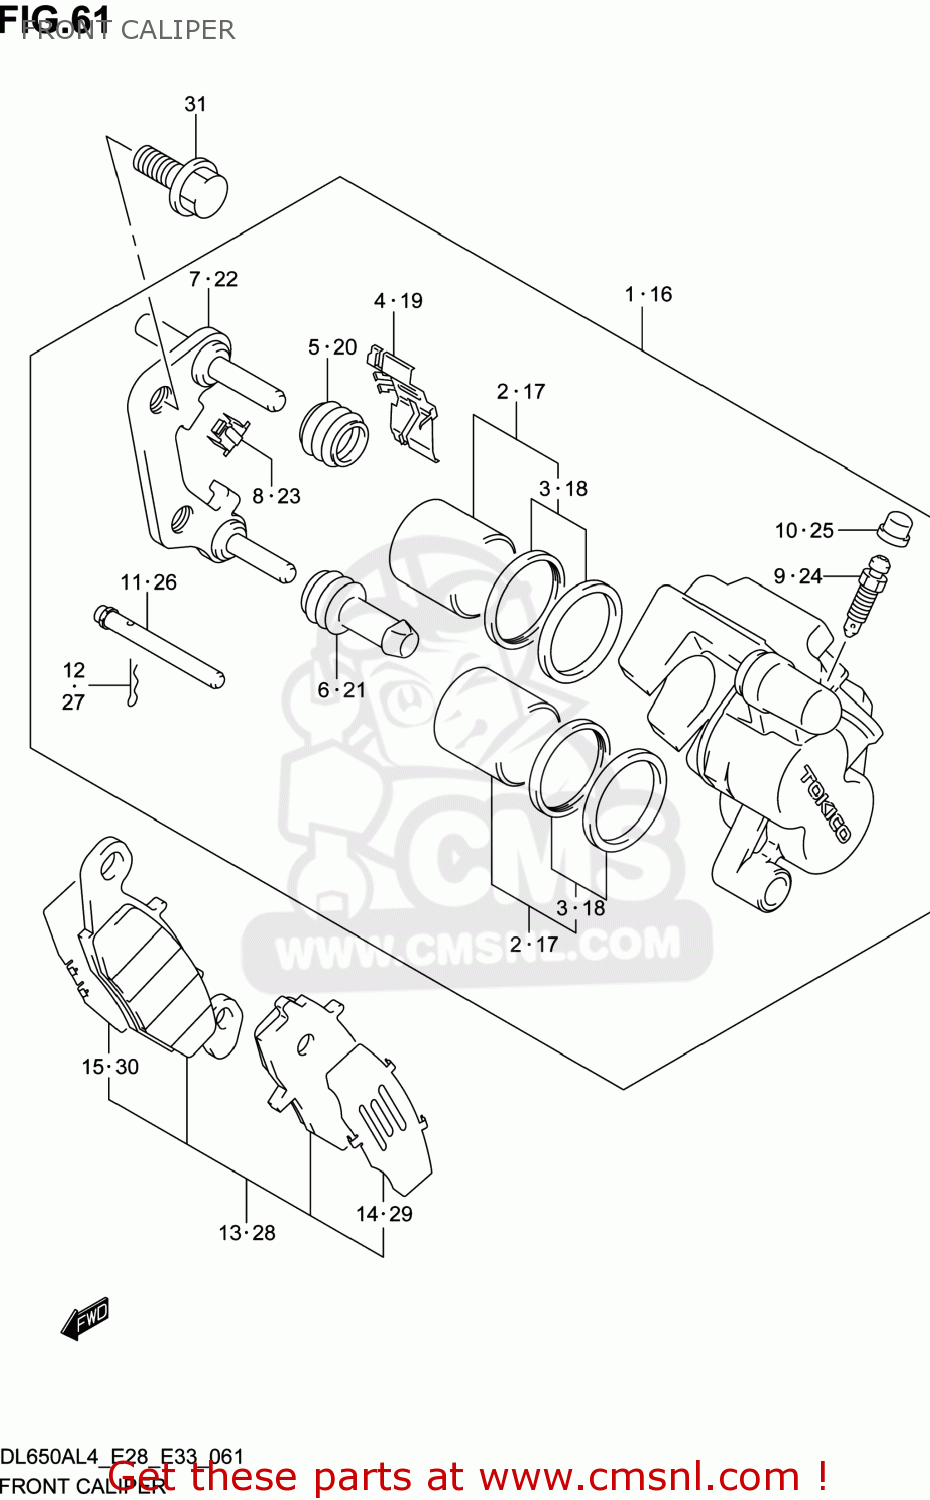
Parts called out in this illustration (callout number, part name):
1	CALIPER ASSY,FR
2	PISTON SET
3	SEAL SET,PISTON
4	SPRING,PAD,R
5	BOOT,AXLE
6	INSULATOR,AXLE
7	CARRIER,CALIPER,R
8	GUIDE,PAD
9	BLEEDER
10	CAP,BLEEDER PLUG
11	PIN,PAD
12	CLIP,PAD PIN
13	PAD & SHIM SET,R (NAS)
14	SHIM,PAD
15	SHIM,PAD NO.2
16	CALIPER ASSY,FR,L
17	PISTON SET
18	SEAL SET,PISTON
19	SPRING,PAD,L
20	BOOT,AXLE
21	INSULATOR,AXLE
22	CARRIER,CALIPER,L
23	GUIDE,PAD
24	BLEEDER
25	CAP,BLEEDER PLUG
26	PIN,PAD
27	CLIP,PAD PIN
28	PAD & SHIM SET,L (NAS)
29	SHIM,PAD
30	SHIM,PAD NO.2
31	BOLT
